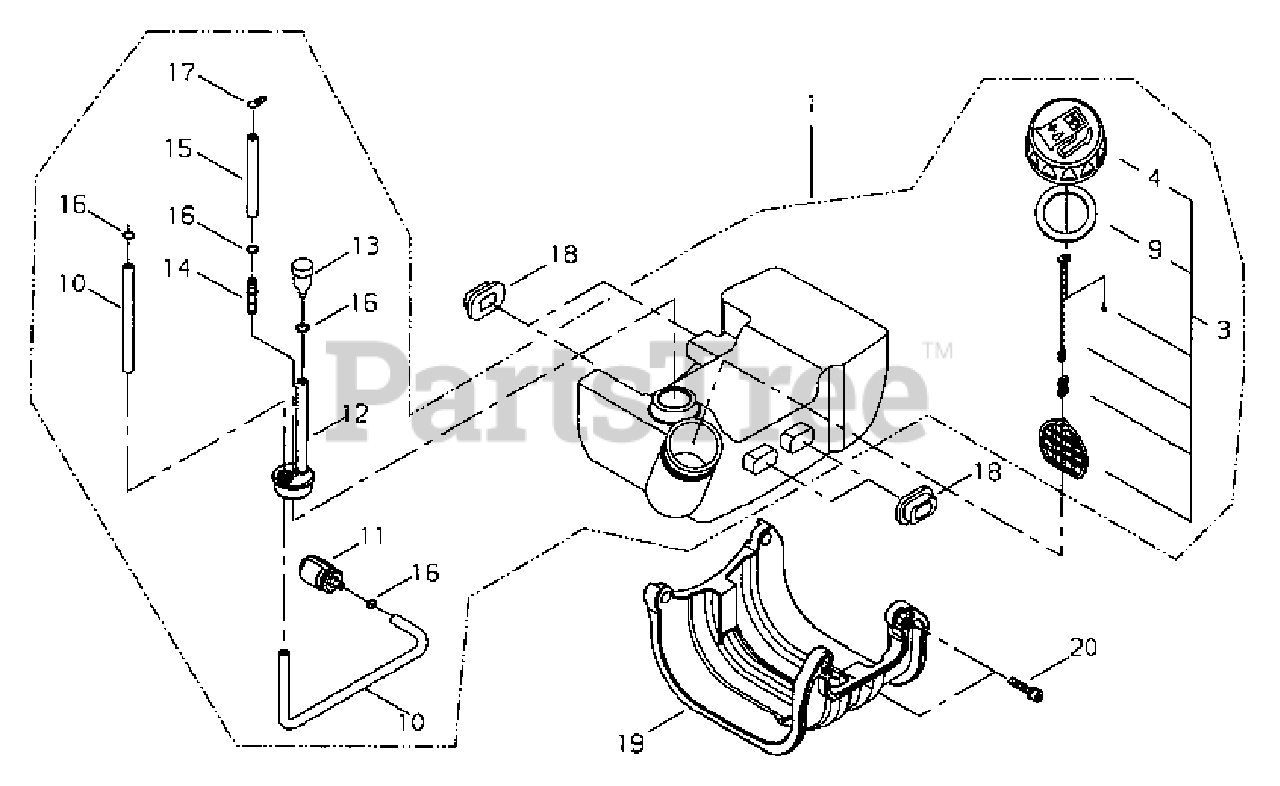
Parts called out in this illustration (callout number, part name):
1	FUEL TANK ASSY
3	CAP ASSY
4	CAP, FUEL
9	GASKET, CAP
10	PIPE - FUEL
11	FILTER, FUEL
12	GROMMET
13	ELEMENT, BREATHER
14	CONNECTOR, PIPE
15	PIPE - RETURN
16	RING, RETAINING - 6
17	CLIP - SPRING
18	CUSHION, FUEL TANK
19	GUARD, FUEL TANK
20	SCREW - 5X20
